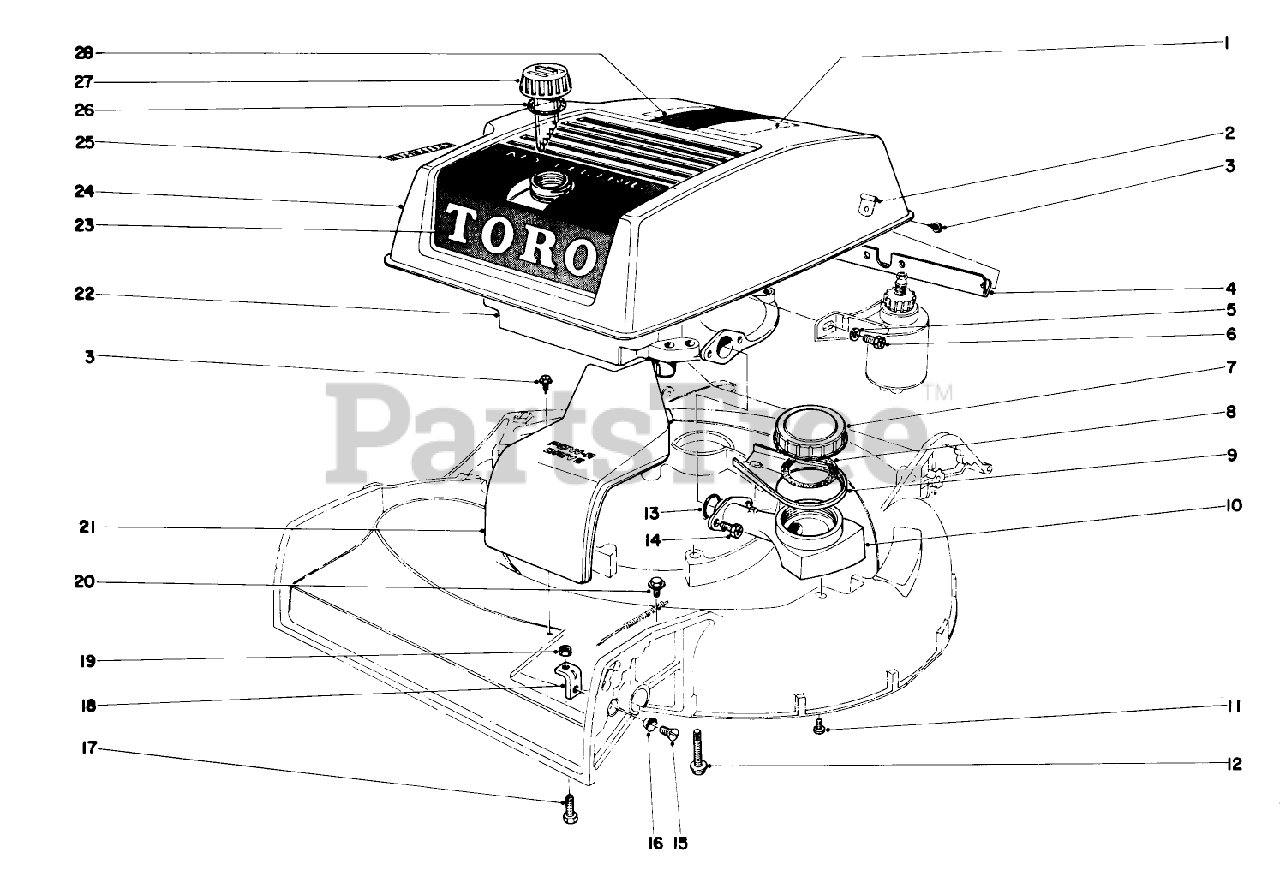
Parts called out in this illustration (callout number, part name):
1	Decal-Maintenance
2	Hinge
3	SCREW-HWHTF
4	Shroud Bracket
5	WASHER-FLAT
10	Oil Gauge
12	3/8-16 X 2-3/4 CAPSCR
13	O RING
15	SCREW-FH, S
19	NUT-JAM
20	SCREW-HHF
22	Engine
23	Decal
24	Shroud
26	Gasket
28	Decal
